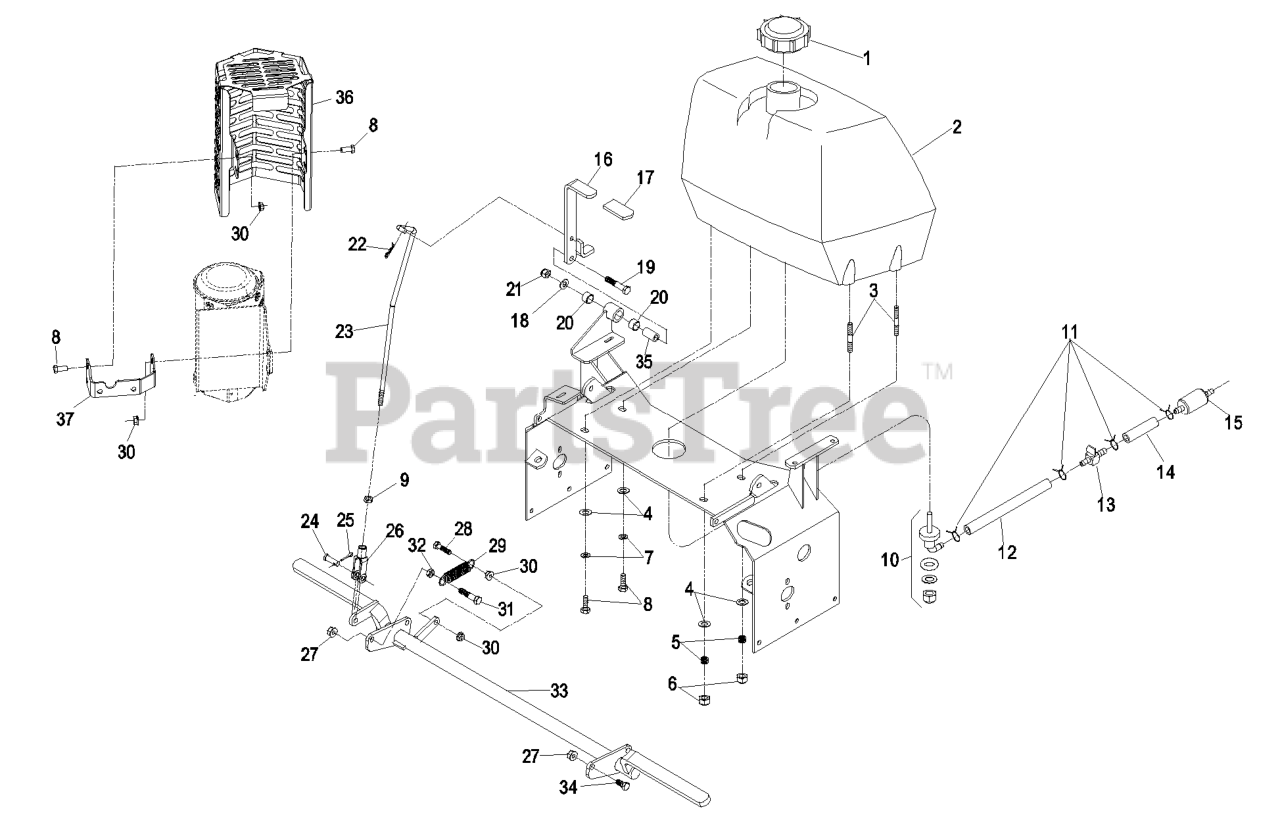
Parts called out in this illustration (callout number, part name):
1	CAP-FUEL, GAS
2	ASM,FUEL TANK W/B
3	STUD
4	WASHER-PLAIN
5	SPRING-TANK, FUEL
6	NUT-LOCK, NI
7	WASHER-LOCK
8	SCREW-HH
9	NUT-HJ
10	FITTING-FUEL, BULKHEAD
12	HOSE-FUEL
13	VALVE-FUEL
14	HOSE-FUEL
15	Kawasaki Part No. 49019-7001 Fuel Filter
16	LEVER,PRK BRK W/DECALS
17	GRIP-LEVER
18	WASHER-FLAT
19	SCREW-HH
20	SLEEVE-BUSHING
21	NUT-LOCK, NI
22	PIN-COTTER
23	LINKAGE, PARK BRAKE
24	PIN-CLEVIS
25	PIN-COTTER
26	YOKE-LINKAGE, BRAKE
27	NUT-HHF, WHIZ
28	SCREW-HH
29	SPRING-IDLER
31	SCREW-HH
32	NUT-JAM
34	SCREW-HH
35	BUSHING-PIVOT
36	MUFFLER SHIELD ASM
37	BRACKET-MUFFLER
